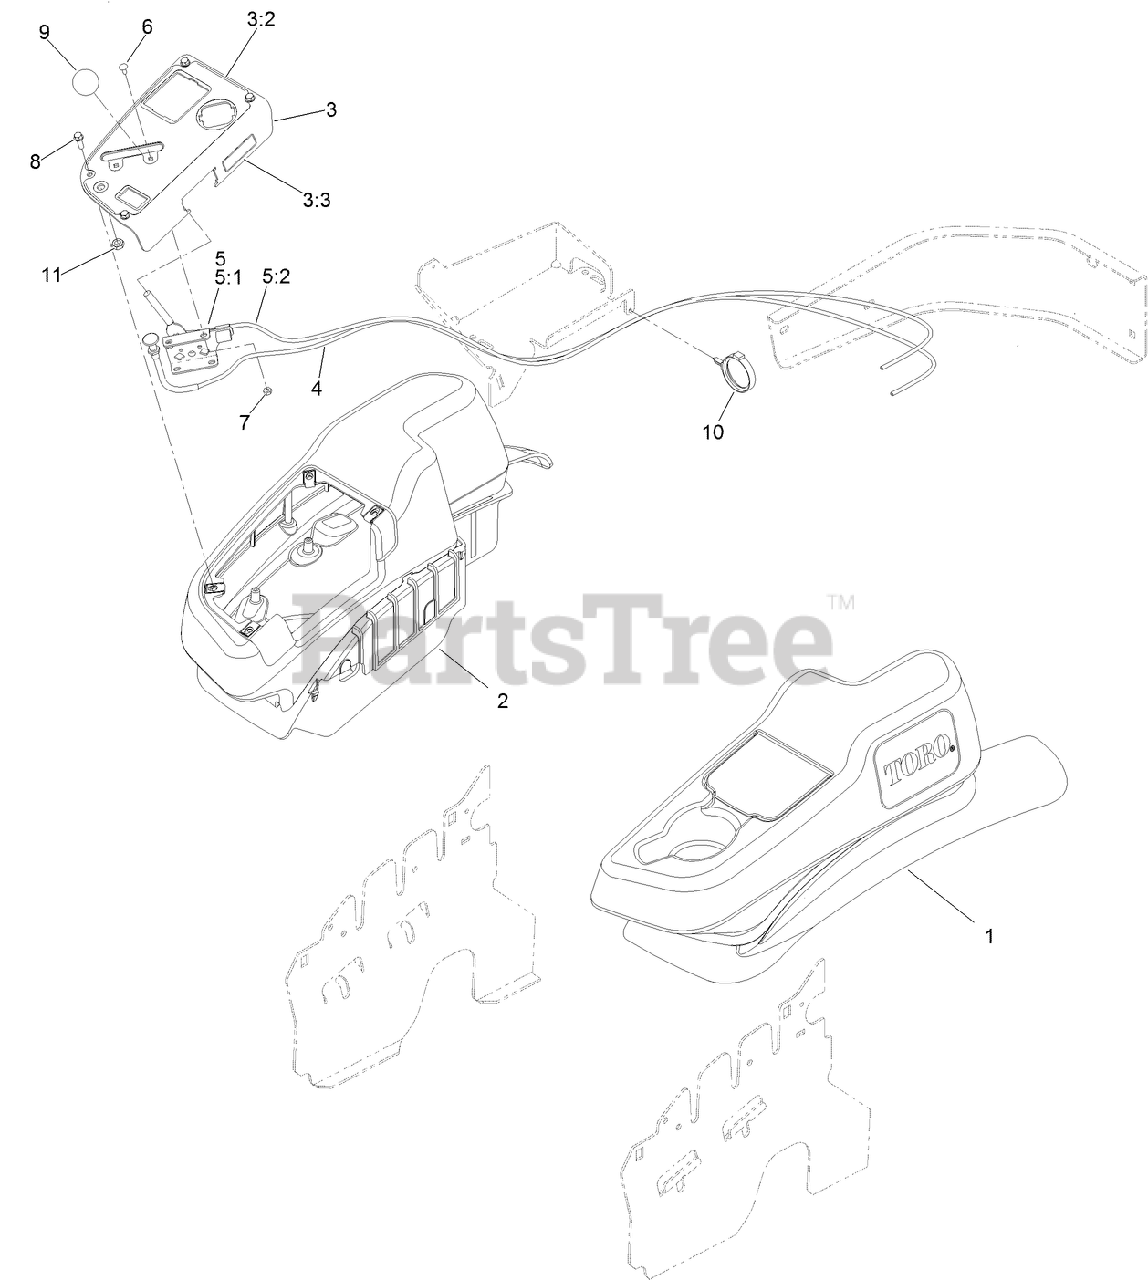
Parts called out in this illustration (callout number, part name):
1	LH NARROW FENDER/CONSOLE ASM
2	RH NARROW FENDER/CONSOLE ASM
3	CONTROL PANEL ASM
3:2	DECAL-CONTROL PANEL
3:3	DECAL-FUSES
4	CONTROL-CHOKE
5	THROTTLE CONTROL ASM
5:1	LEVER-THROTTLE
5:2	CABLE-THROTTLE
6	BOLT-CARR
7	NUT-LOCK, NI
8	SCREW-HWH
9	KNOB-BALL
10	CLAMP-HARNESS
11	NUT-HJ
